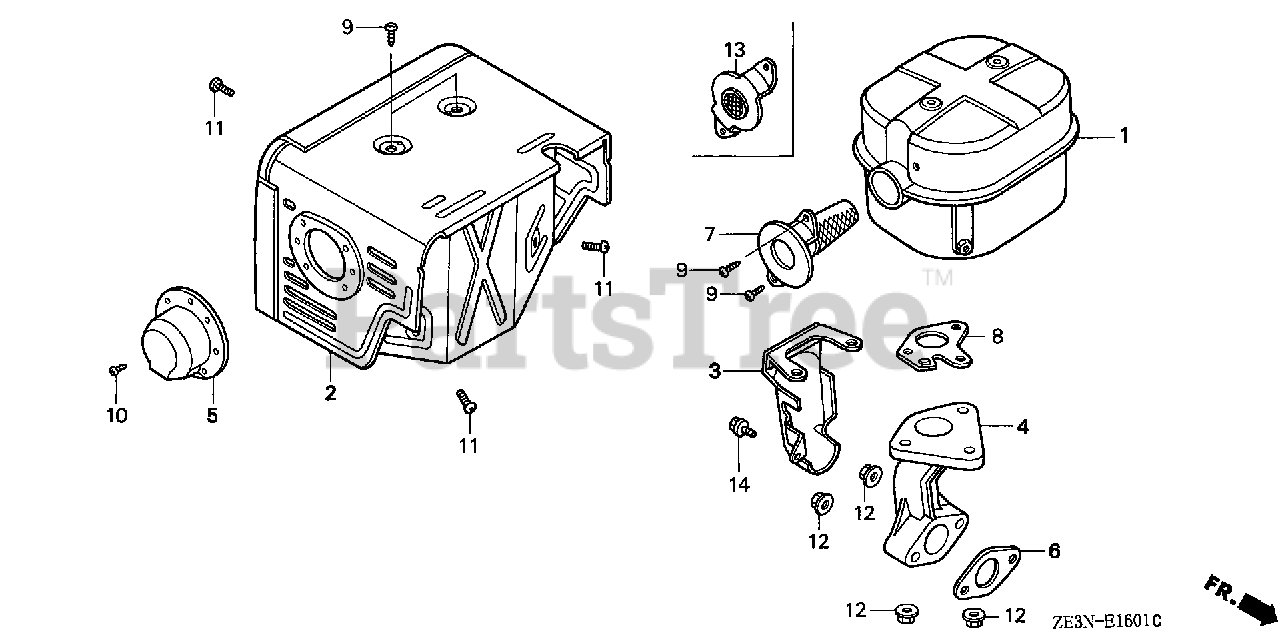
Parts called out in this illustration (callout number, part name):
1	MUFFLER
2	PROTECTOR, MUFFLER
4	PIPE, EX.
5	CAP, MUFFLER
6	GASKET, EX. PIPE
7	ARRESTER, SPARK
8	GASKET, MUFFLER (ARRESTER)
8	GASKET, MUFFLER
9	SCREW, TAPPING (5X8)
10	SCREW, TAPPING (4X6)
11	SCREW, PAN (6X6)
12	NUT, FLANGE (8MM)
13	FLANGE, BAFFLE
